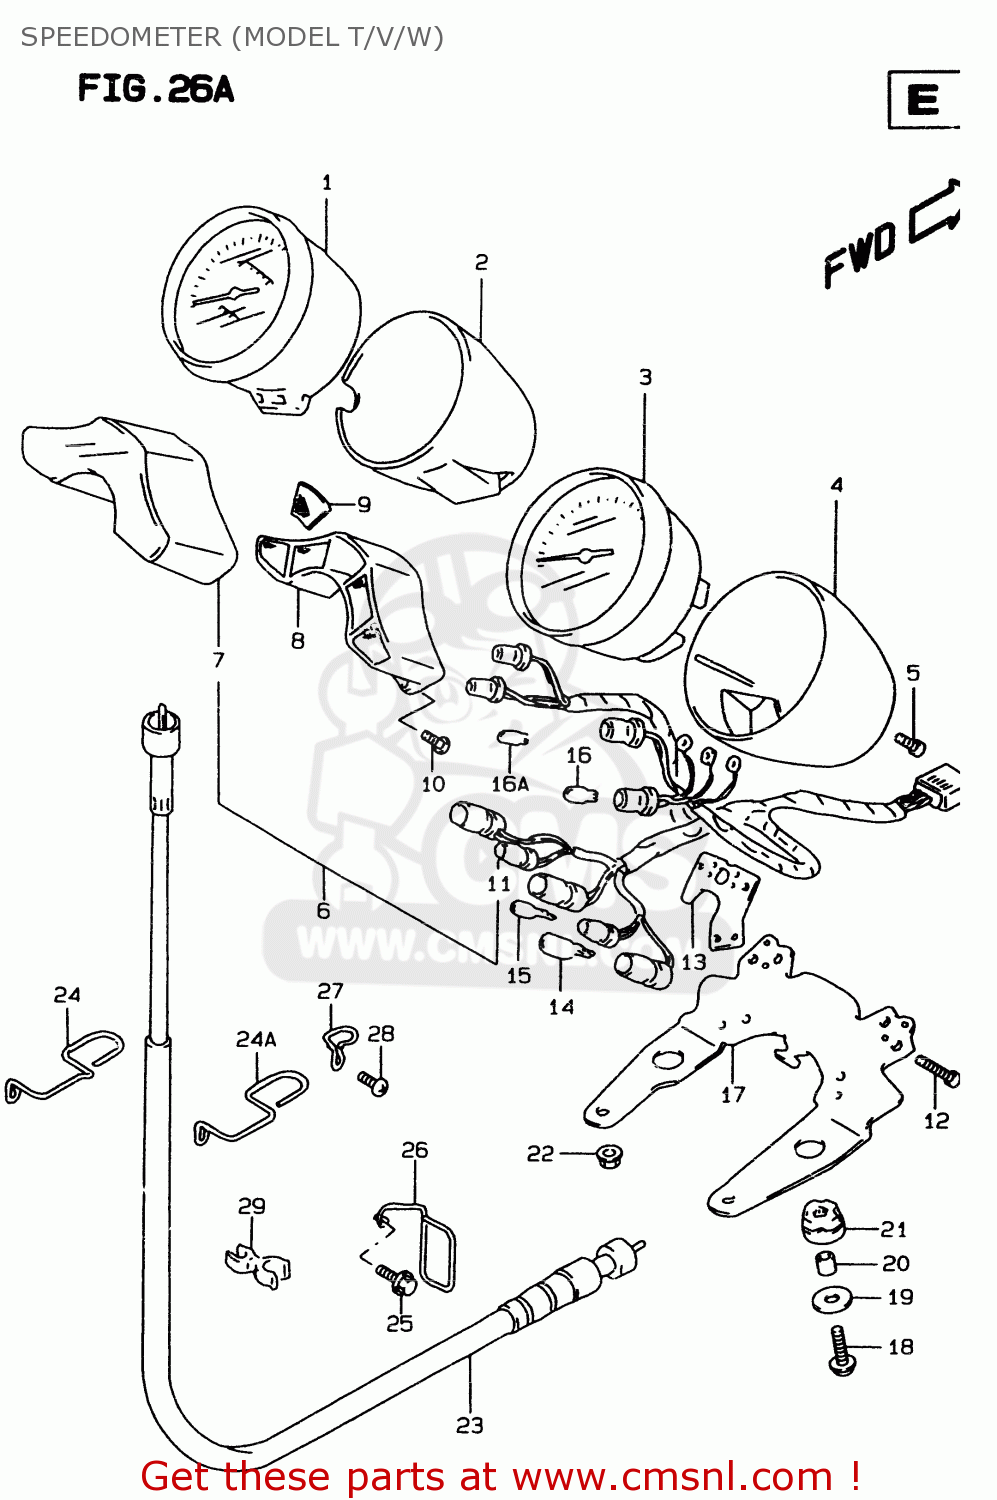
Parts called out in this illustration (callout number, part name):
1	SPEEDOMETER
2	LWR CASE,SPEEDOMETER
3	TACHOMETER
4	LOWER CASE,TAC
5	SCREW
6	BOX, PILOT
7	CASE,UPR
8	INNER CASE
9	LENS SET,PILOT
10	SCREW
11	SOCKET
12	SCREW
13	PLATE
14	BULB(12V3.4W,T10,BF175-01450A)
15	BULB(12V3W,WB371,T7)
16	BULB(12V1.7W,WB372,T7)
16A	BULB(14V,0.84W)
17	BRACKET,METER
18	BOLT
19	WASHER(6.5X20X1.6)
20	SPACER(6.5X9X15.5)
21	CUSHION
22	NUT
23	CABLE ASSEMBLY,SPEEDOMETER
24	GUIDE,SPEEDOMETER CABLE NO.2
24A	GUIDE,SPEEDOMETER CABLE
25	BOLT
26	GUIDE,SPEEDOMETER CABLE
27	GUIDE,METER CABLE NO.1
28	SCREW 6X10
29	CLIP
